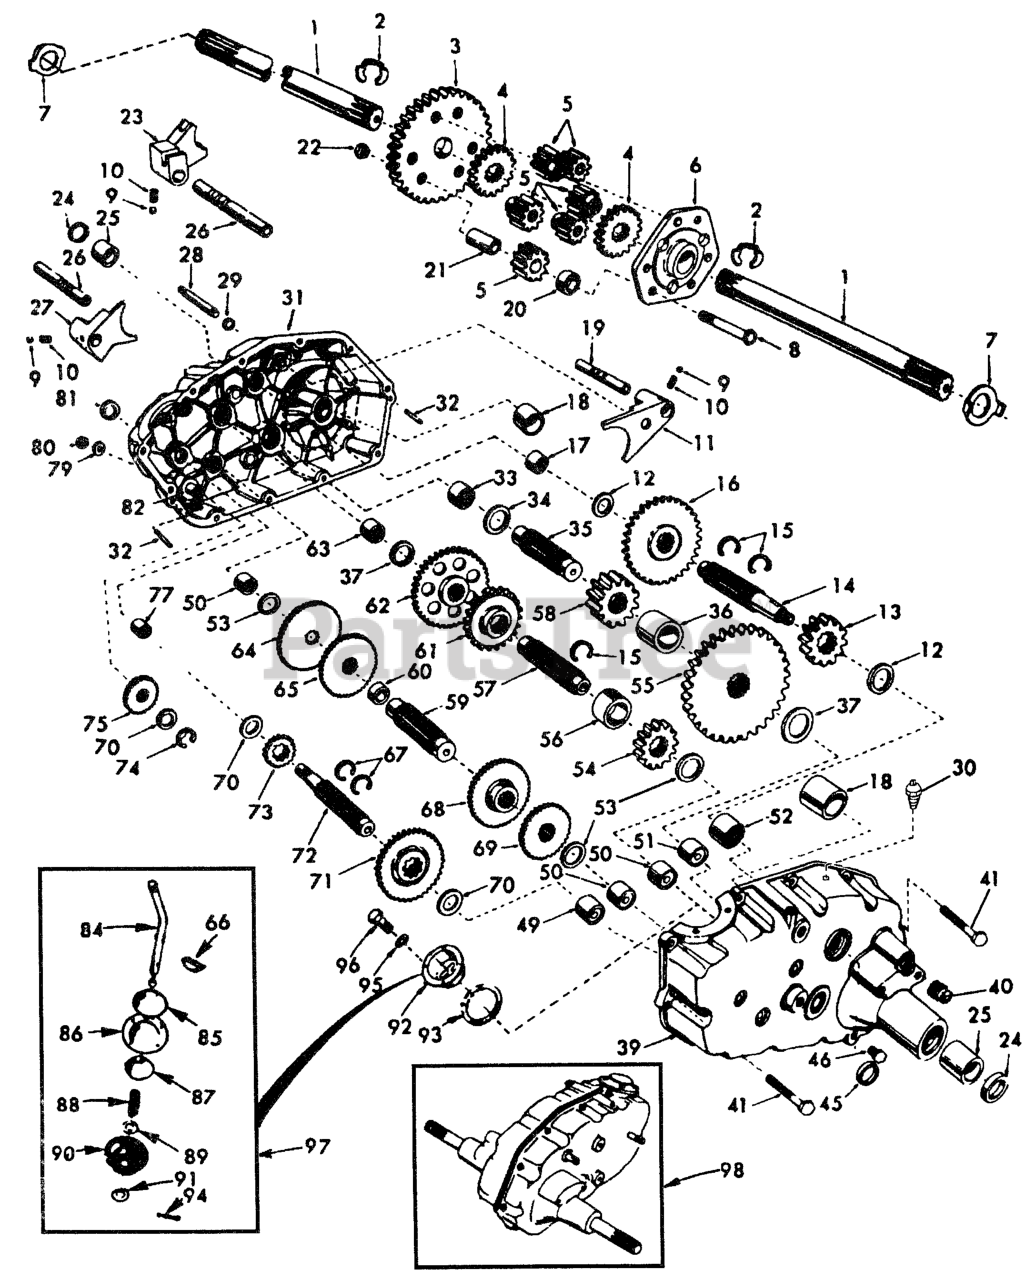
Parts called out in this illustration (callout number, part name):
1	AXLE SHAFT T
2	Retaining Ring
3	FINAL GEAR T
4	DIFF GEAR T
5	DIFF PINION T
6	DIFF CARRIER T
7	WASHER T
8	Bolt, Hex Head 3/8-24 x 3-1/4 (1" Thread Length)
9	STEEL BALL KIT
10	SPRING
12	THRUST WASHER
13	RED PINION T
14	GEAR SHAFT
15	SNAP RING T
16	GEAR T
18	BEARING
21	PINION RS
22	GRIPCO NUT
24	OIL SEAL STD
25	BRNG. T
26	SHAFT SHIFT FORK
27	SHIFT FORK T
28	SHIFT SHAFT
29	SEAL.OIL.SHAFT.SHIFT.T
31	GEARCASE.RH.W/BEARING
33	NEEDLE BRNG T
34	WASHER RACE BEARING THRUST
35	GEAR SHAFT T
36	GEAR SPACER T
39	GEARCASE LH
40	Pipe Plug 1/2-14 N.P.T.
41	BOLT.5/16-18X1.25
49	BEARING TI
50	NEEDLE BRNG T
51	NEEDLE BRNG T
52	BEARING STD
53	BRNG RACE T
54	RED PINION T
55	RED GEAR T
56	PINION SPACER T
57	GEAR SHAFT T
58	FINAL PINION T
59	GEAR SHAFT T
61	RED PINION T
62	RED GEAR T
64	LOW SPEED GEAR T
65	GEAR.REVERSE.T
67	Snap Ring, Crescent Type
68	GEAR.SPEED.INTERMEDIATE.T/A
69	HIGH SPEED GEAR T
70	THRUST WASHER
71	CLUSTER GEAR T
72	SHAFT
73	LO SPEED PINION T
75	IDLER GEAR T
77	NEEDLE BEARING TI
80	NUT **
81	SEAL STD
82	SHAFT REVERSE IDL
84	GEAR SHIFT LVR T
86	COVER AND PIN T
87	GUIDE BALL T
89	WASHER
90	SEAL.SHIFT
91	Washer 9/16 x 15/16 x 12 Gauge
92	GEAR SHIFT GATE T
94	COTTER PIN
95	WASHER.LOCK.HVY.HLCL.SPR.5/16
96	BOLT
97	GEAR SHFT LVR T
98	TRANSAXLE ASSY
